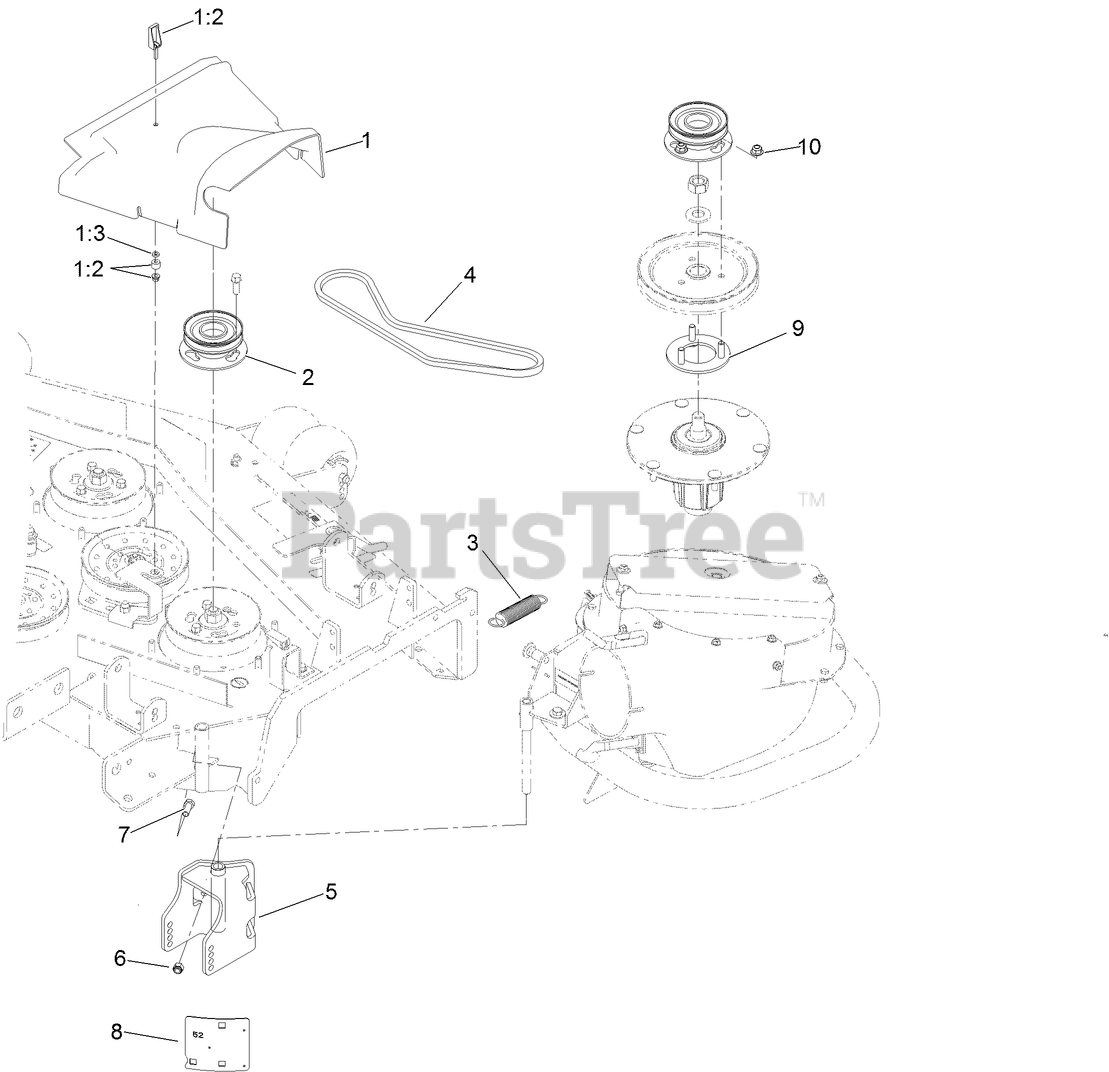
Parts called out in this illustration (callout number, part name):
1	BELT COVER ASM
1:2	LATCH-SWELL
1:3	WASHER
2	PULLEY-BLOWER
3	SPRING-EXTENSION
4	BELT-V
5	BLOWER-HINGE ASM
6	NUT-LOCK, NI
7	SCREW-HH
8	TEMPLATE
9	PULLEY MOUNT ASM
10	NUT-HF, NI
